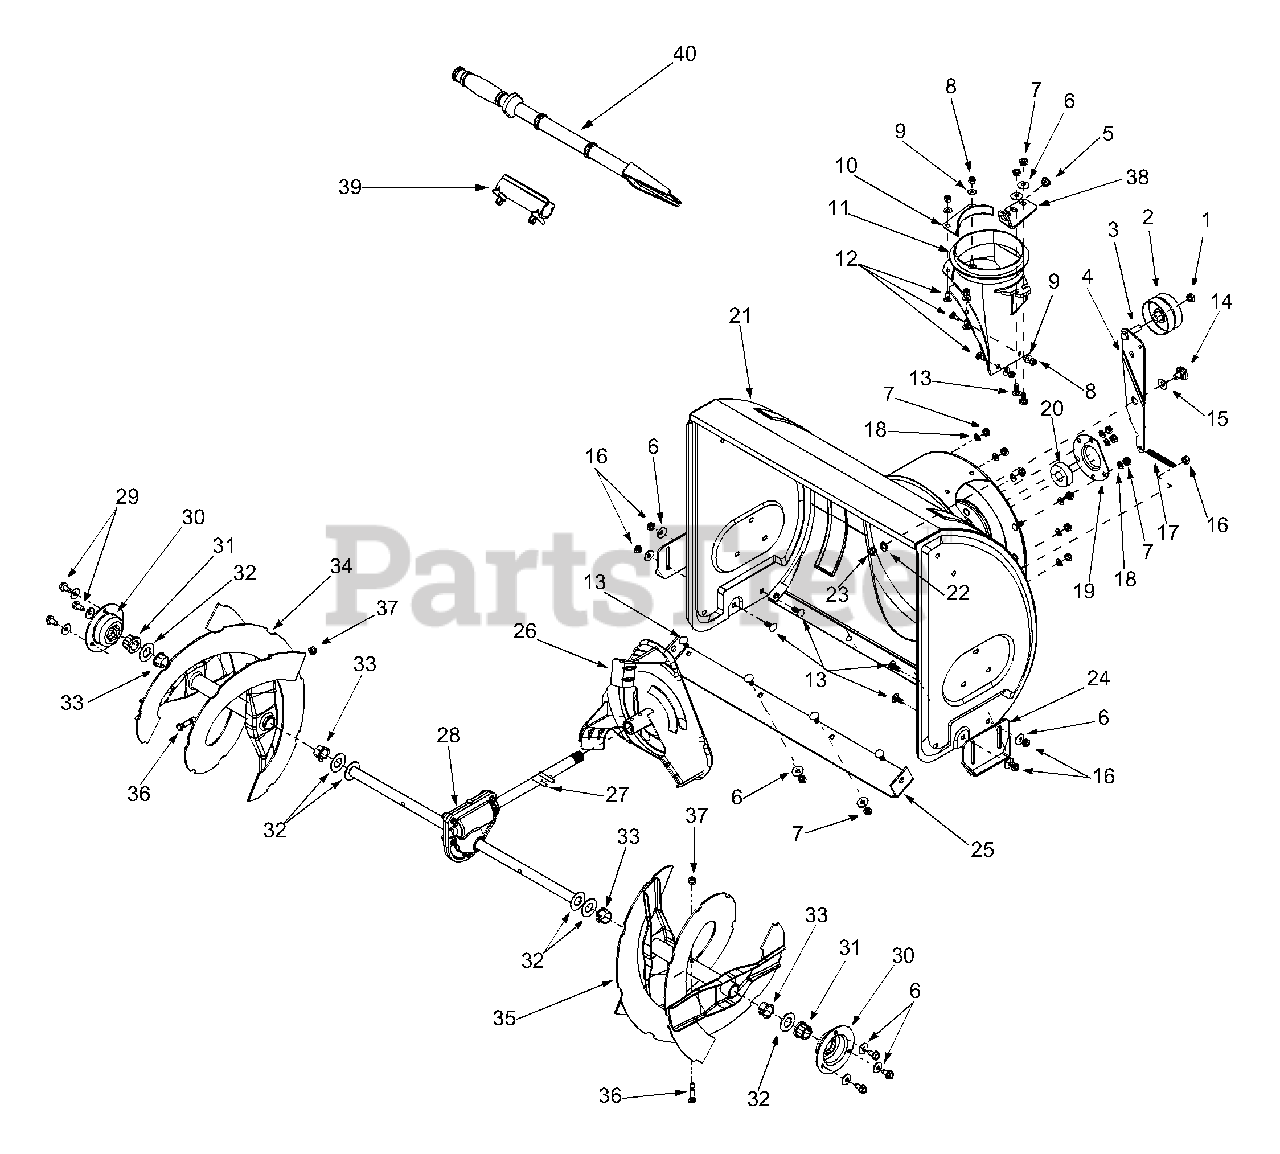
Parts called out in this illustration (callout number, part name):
1	Lock Jam Nut 3/8-24
2	Flat Idler
4	Hex Cap Screw 3/8-24 x 1.50
5	Bushing
6	Bell Washer
7	Hex Nut 5/16-18
8	Hex Lock Nut 1/4-20
9	Flat Washer
11	Chute Adapter
12	Carriage Screw 1/4-20 x .62
13	Carriage Bolt 5/16-18
14	Shoulder Screw
15	Flat Washer
16	Hex Nut 5/16-18
17	Extension Spring
18	Lock Washer 5/16
19	Bearing Housing
20	Ball Bearing
23	Hex Nut 3/8-16
28	24" Gear Assembly
29	Hex Washer Screw 5/16-18
31	Hex Flange Bearing
32	Flat Washer
33	Flange Bushing
37	Lock Nut 5/16-18
39	Clean-Out Tool Mount
40	Clean-Out Tool
